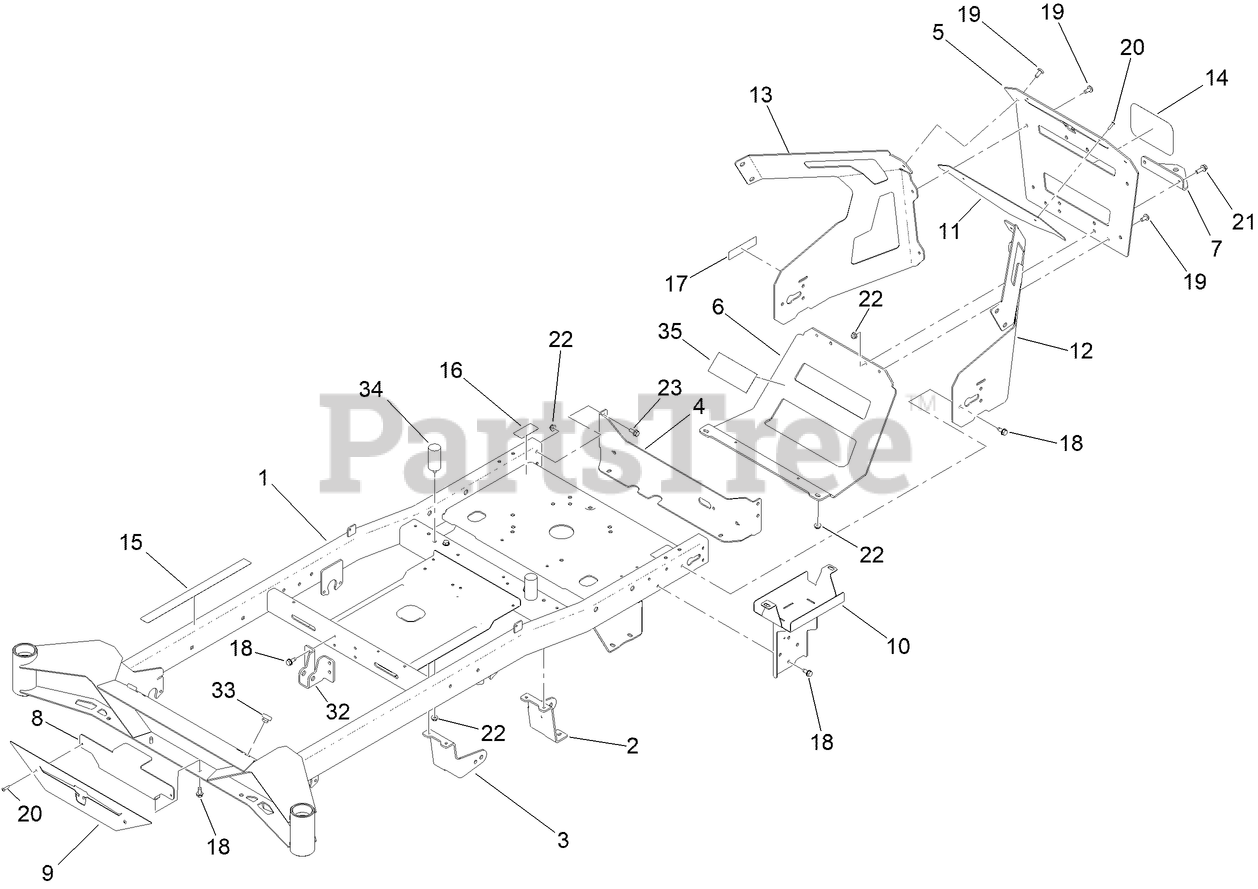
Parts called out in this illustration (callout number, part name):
1	SERVICE ASM-FRAME, TITAN
2	MOUNT-DRIVE, LH
3	MOUNT-DRIVE, RH
4	PLATE-MOUNT
5	GUARD-ENGINE
6	GUARD-MUFFLER
7	BRACKET-HITCH
8	PLATE-BACKER
9	LOGO-PLATE-FRONT
10	WA-BATTERY MOUNT
11	PLATE-BACKER
12	GUARD-ENGINE LH
13	GUARD-ENGINE-RH
14	DECAL
15	DECAL-WARNING
16	DECAL-BYPASS
17	DECAL-SPARK ARRESTER
18	SCREW-HWHTF
20	RIVET-TRIFOLD
21	SCREW-HHF
22	NUT-HF
23	SCREW-HHF
32	BRACKET-MOUNT DAMPER, LOWER
33	BUMPER-RUBBER
34	BUMPER-RUBBER
35	TAPE-HEAT
